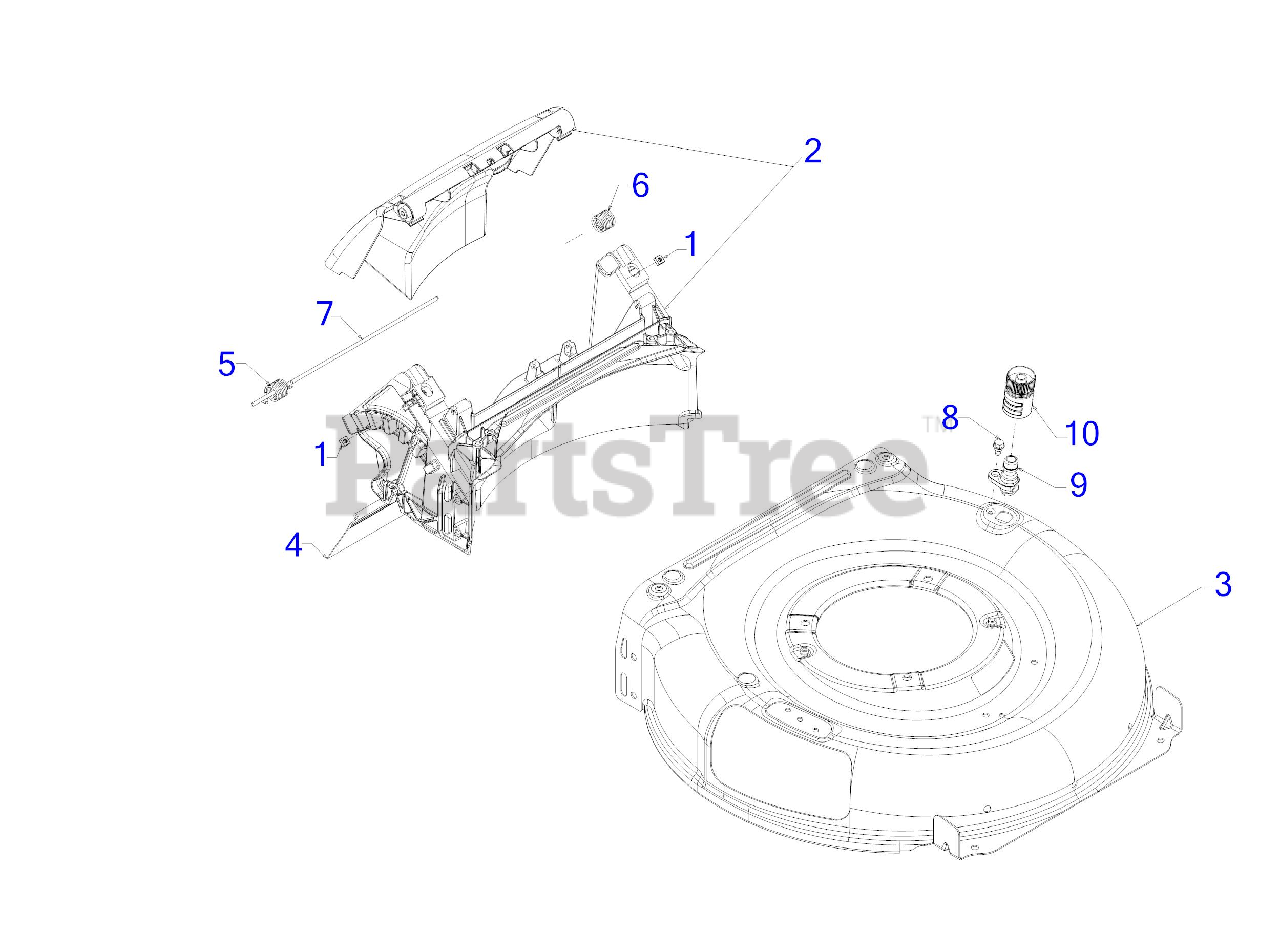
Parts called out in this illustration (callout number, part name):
1	SQUARE NUT 1/4-20
2	REAR BAG DOOR ASSEMBLY
3	21" DECK (3N1)
4	TRAILSHIELD
5	TORSION SPRING (RH)
6	TORSION SPRING (LH)
7	REAR DOOR PIVOT ROD
8	WATER NOZZLE
9	DECK WASH NOZZLE
10	SHOULDER SCREW 1/4-20 x .50
